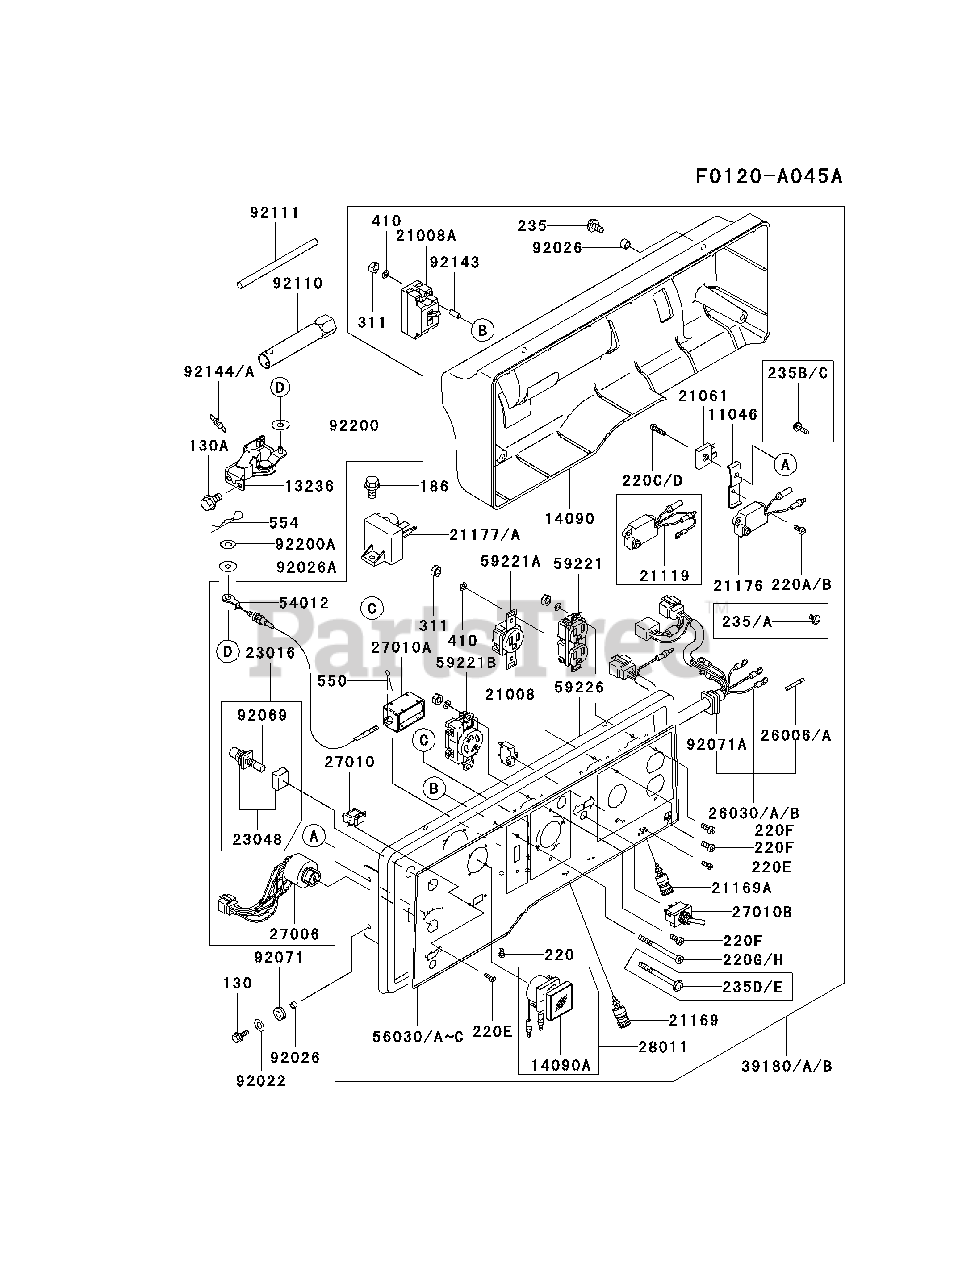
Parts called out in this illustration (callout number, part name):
130	BOLT-FLANGED
130A	BOLT-FLANGED
186	BOLT-UPSET-WP
220	SCREW-PAN-CROS
220B	SCREW-PAN-CROS
220C	SCREW-PAN-CROS
220E	SCREW-PAN-CROS
220F	SCREW-PAN-CROS
220G	SCREW-PAN-CROS
235	SCREW-PAN-WP-CROS
235A	SCREW-PAN-WP-CROS
311	NUT-HEX
410	W-PLAIN-S
550	PIN-COTTER
92110	TOOL-WRENCH,21
92200	WASHER,5.2X16X1
92200A	WASHER,5.5X13.8X1.2
